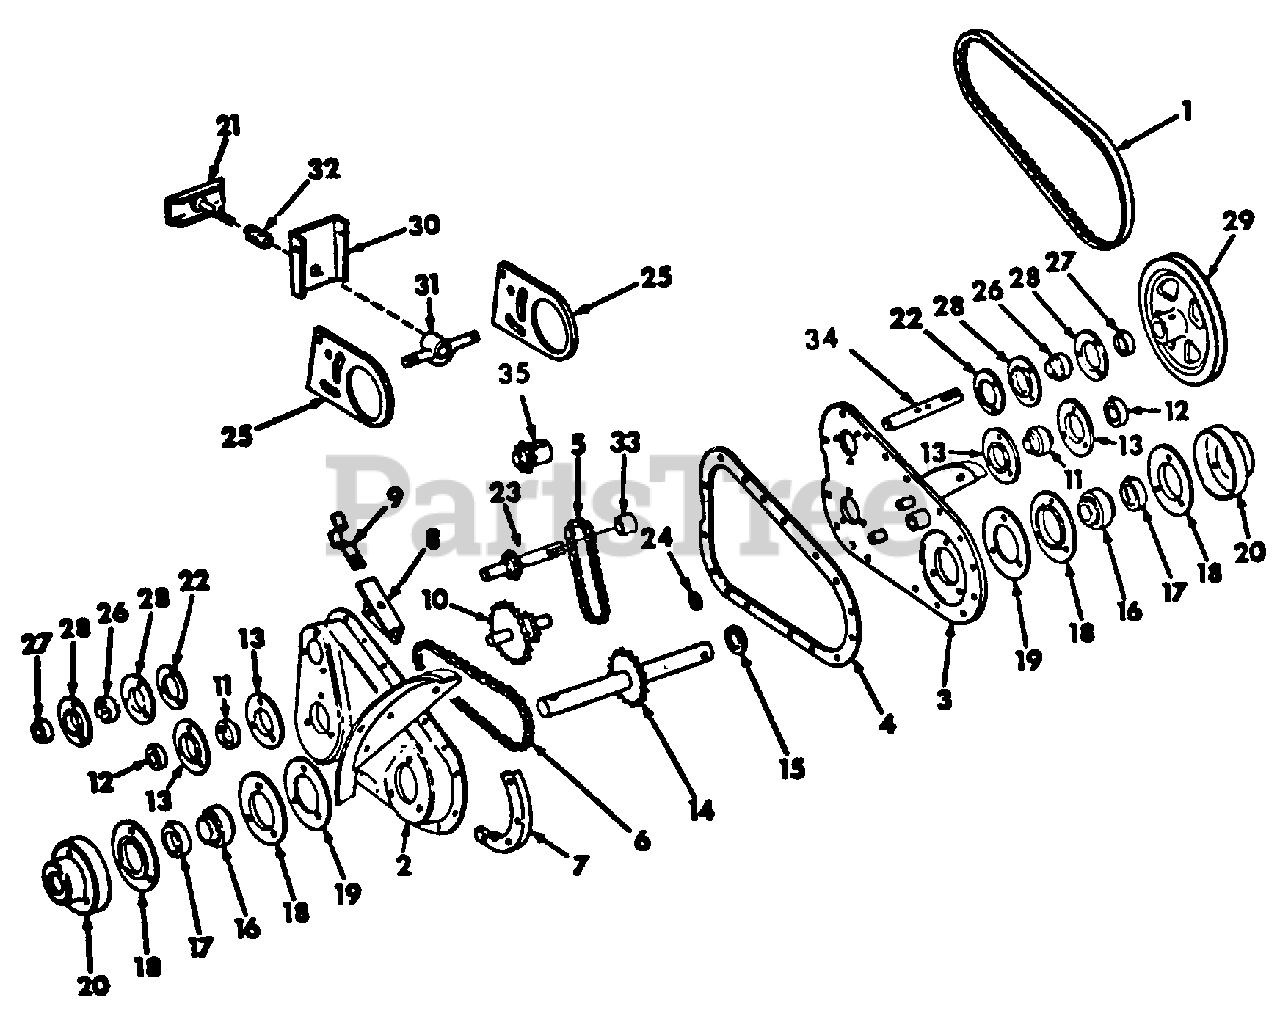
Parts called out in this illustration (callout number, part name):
1	Belt, Drive
2	Housing Assy, Chain Drive
3	Plate, Housing Back
4	Gasket, Chain Drive Housing
5	Chain, Main Drive
6	Chain, Tine Drive
7	Shoe, Formed
8	Clip, Mounting Bracket
9	Clip, Retainer
10	Sprocket Assy, Idler -10 & 28 T
11	Bearing Assy, w/o Locking Collar
12	Collar, Locking w/Set Screw
13	Flange, Bearing
14	Shaft Assy, Main Drive -18 T
16	Bearing w/o Locking Collar
17	Collar, Locking w/Set Screw
18	Flange, Bearing
19	Gasket, Flange
20	Dust Excluder
21	Tee Assy, Belt Adjustment
23	Shaft, Input -For 1A Tiller
24	Seal, Adhesive Dust
25	Plate, Pivot
26	Bearing w/o Locking Collar
27	Collar, Locking
28	Flange, Bearing
29	Pulley, Drive
30	Channel, Belt Tightener
31	Adjustment Assy
32	Spring, Compression
33	Spacer, Input Shaft -For 1A Tiller
34	Shaft, Input -For 1 Tiller
35	Sprocket -12 T- -For 1 Tiller
